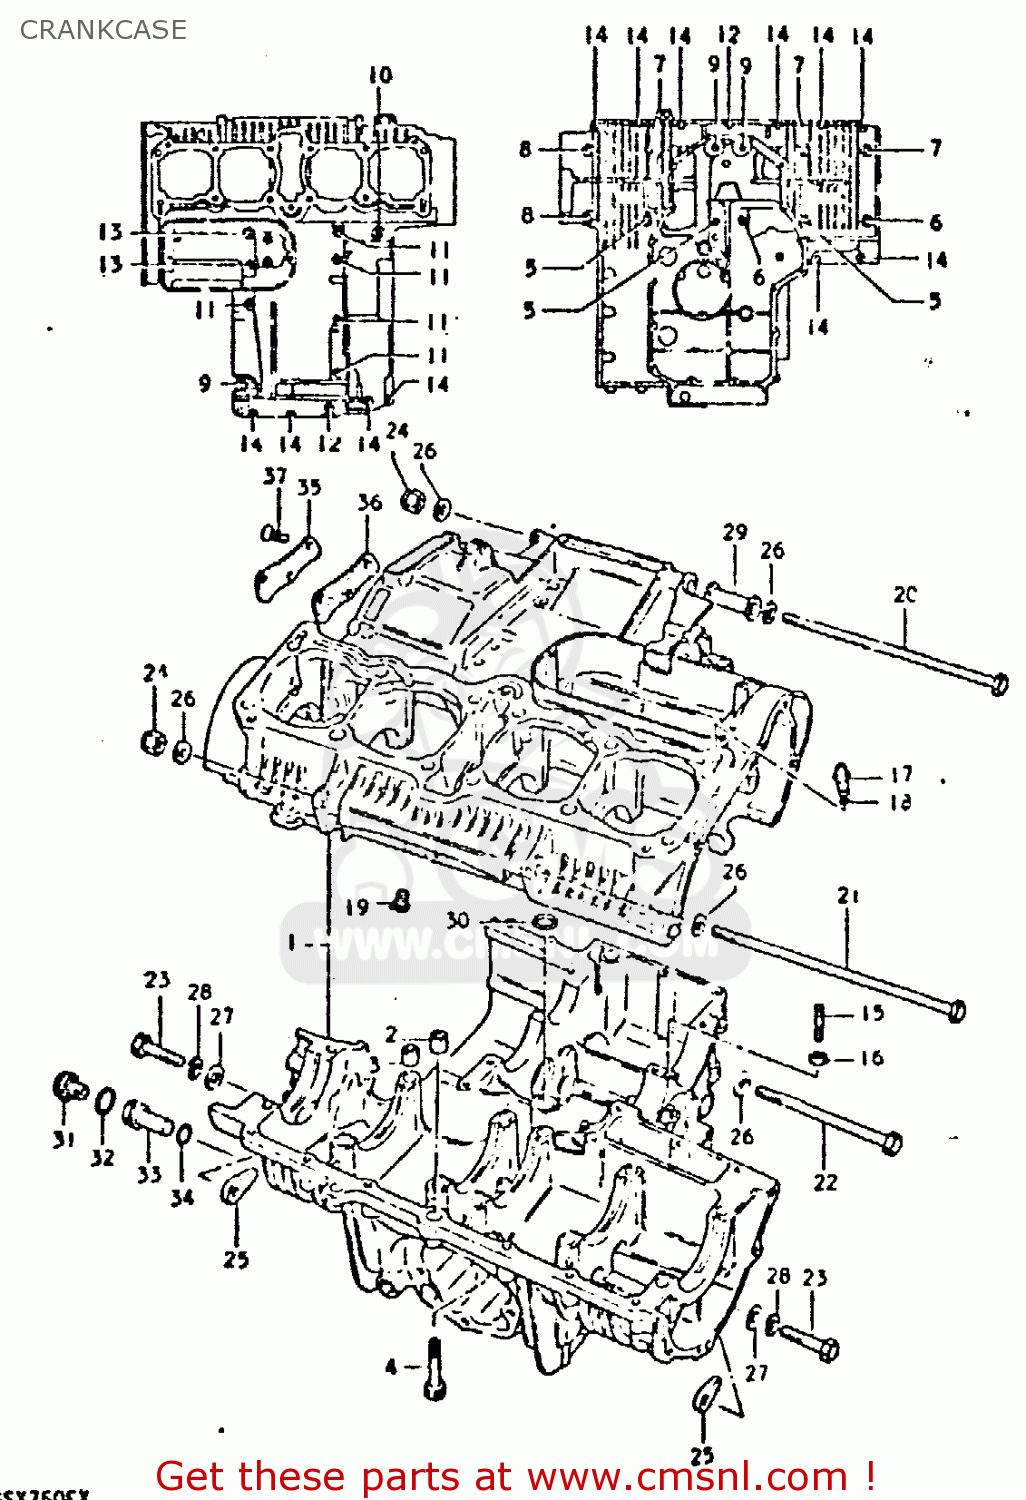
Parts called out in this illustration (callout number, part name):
1	CRANKCASE SET
2	PIN(10.4X13X22)
3	PIN (11X20)(SUS)
4	BOLT
5	BOLT(8X140)
6	BOLT
7	BOLT (8X95)
8	BOLT (8X70)
9	BOLT 8X65
10	BOLT (8X95)
11	BOLT (6X80)
12	BOLT
13	BOLT,UNDER
14	BOLT
15	STUD BOLT
16	NUT
17	JET
18	O-RING
19	JET,AIR
20	BOLT 10X230
21	BOLT 10X250
22	BOLT(10X165)
23	BOLT 10X60
24	NUT
25	NUT
26	WASHER
27	WASHER(10.5X20X3.2)
28	LOCK WASHER
29	SPACER
30	O RING(D:3.2,ID:12.9)
31	PLUG
32	O RING(D:2.4,ID:17.8)
33	PIN,OIL GALLERY
34	SEAL (D:1.9 ID:9.8)
35	CAP,OIL GALLERY
36	GASKET,OIL GALLERY (MCA)
37	SCREW
